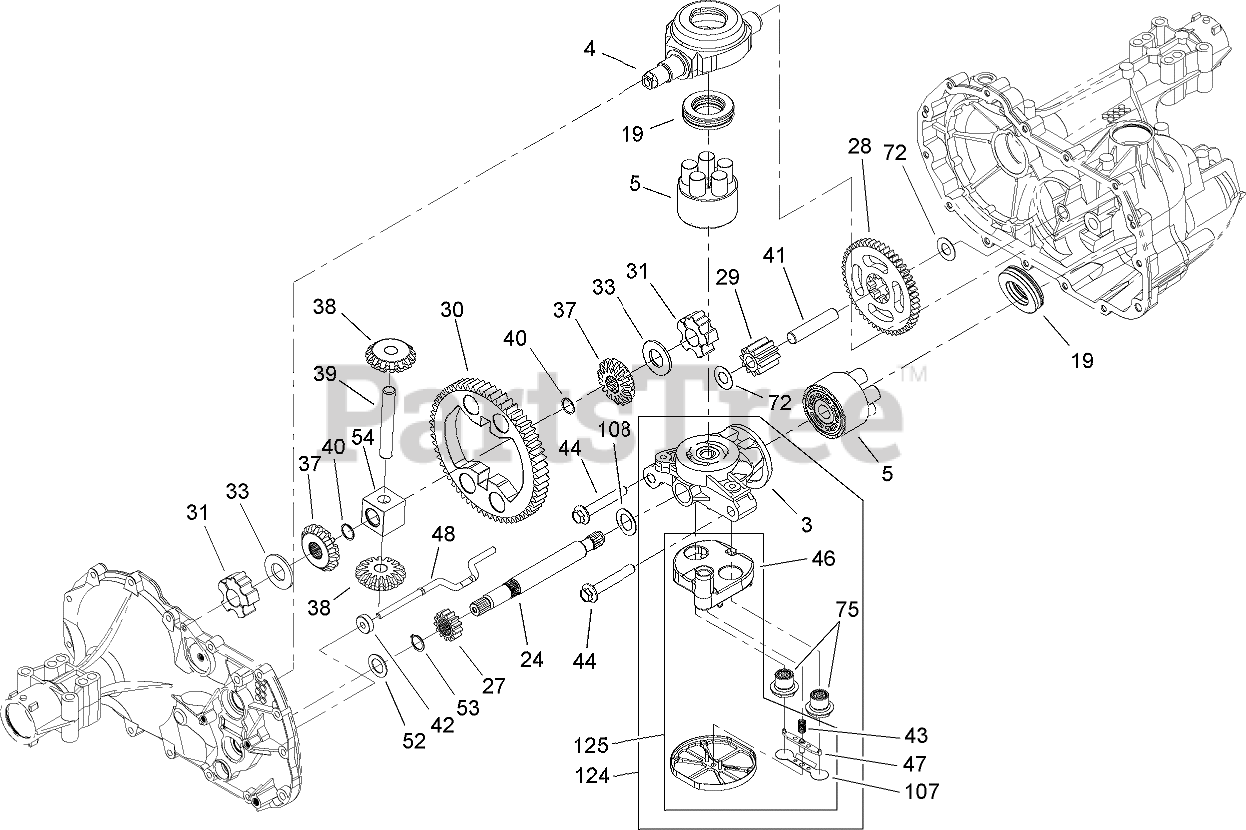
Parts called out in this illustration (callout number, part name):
3	CENTER SECTION ASM
4	SWASHPLATE-TRUNNION
5	CYLINDER BLOCK ASM
19	BEARING-THRUST
24	Shaft-Motor
27	GEAR-PINNION, 13T
28	GEAR-10T/48T
29	GEAR-JACKSHAFT, 10T
30	GEAR-BULL 60T
31	BEARING-SLEEVE
33	WASHER
37	GEAR-MITER
38	GEAR-MITER 15T
40	RING-RETAINING, SPIRAL
41	PIN-JACKSHAFT
42	MAGNET-RING
43	SPRING-BYPASS
46	BASE-FILTER
47	ACTUATOR-BYPASS
48	ROD-ACTUATOR, BYPASS
52	WASHER-FLAT
53	RING-RETAINING
54	BEARING-BLOCK, CENTER
72	WASHER
75	CHECK PLUG ASM
107	DEFLECTOR
108	WASHER
124	CENTER SECTION FILTER BYPASS ASM
125	FILTER ASM
